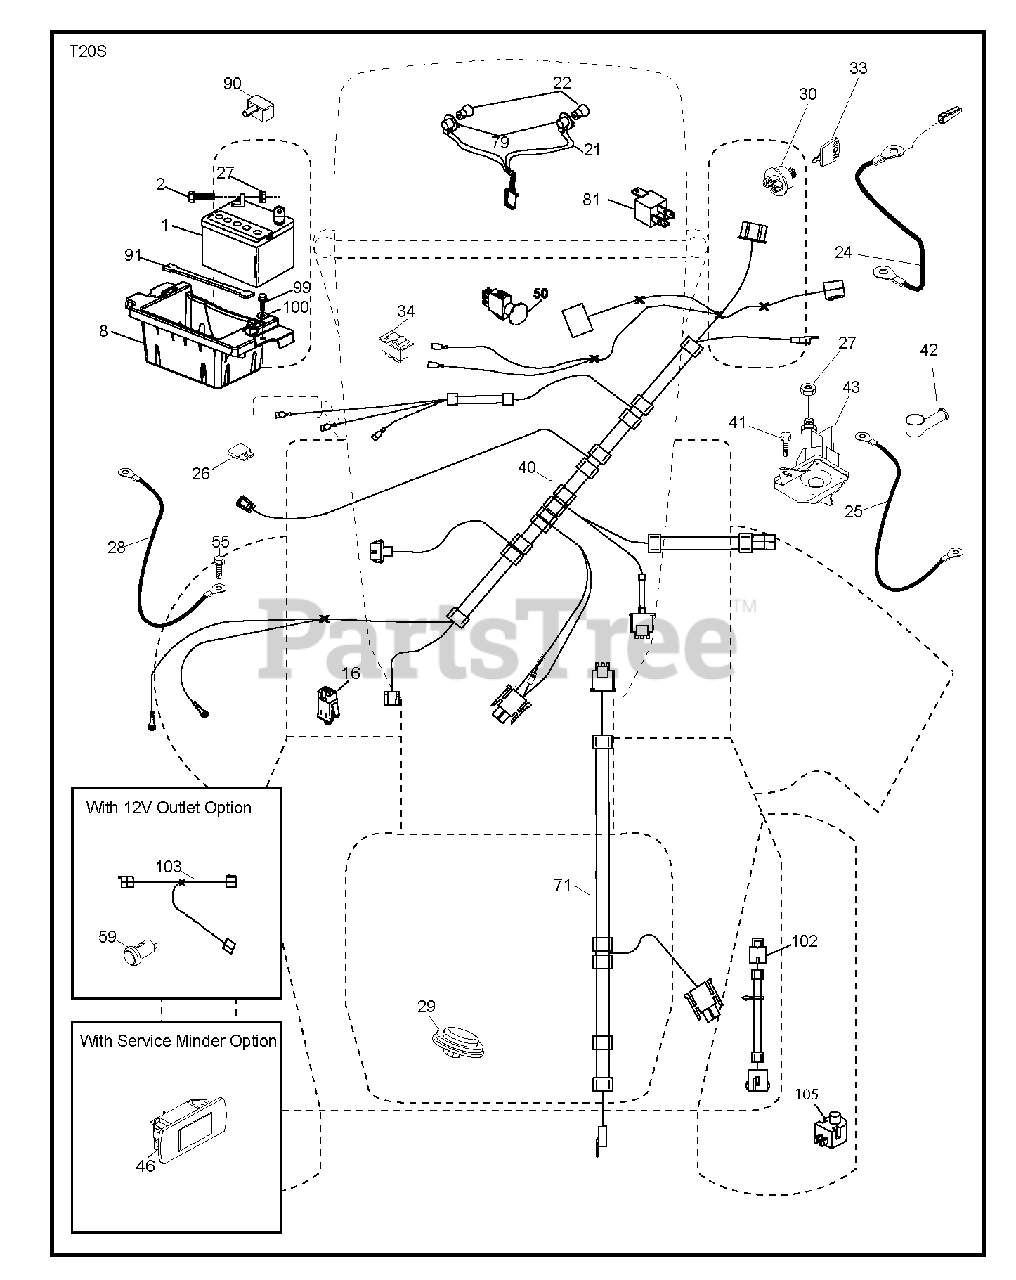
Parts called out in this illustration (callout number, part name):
1	Battery, Dry 30 Amp
2	BOLT.HEX.1/4.X.3/4.DICHROMATE
8	BOX.BATTERY.MOUNT.FRONT.LT
16	SWITCH INTERLOOK PUSH-IN
21	HARNESS.LIGHT W/4152J BULBS
24	CABLE.BATT.POS.WIRE.TG.DA SOL
25	CABLE.STARTER.6G.BL/RED.17.5
26	FUSE 20AMP
27	NUT
28	CABLE GROUND 6 GA 21" 90T BLK
29	SWITCH.SEAT.DELTA.OPC.
30	SWITCH.IGN.DELTA.W.LGH.ROS
33	KEY.CHAIN.BLISTER.PACK.GEN.USA
40	HARNESS.IGN.ELE.RELAY.TEX.46"
41	SCREW
42	TERMINAL COVER
43	SOLENOID.W/BRASS.PLUNGER
46	RP GUAGE.SRVCMNDR.HRMTR.
50	RB PTO.SWITCH.8 TERMINAL.BLACK
55	SCREW 5/16"
71	HARNESS-CHASSIS SUB
79	BULB HOLDER ASM.
81	RELAY HARNESS.SEALED
90	COVER.TERMINAL.BATTERY
91	STRAP.BATTERY.MOUNT.FRONT(2 2)
99	SCREW HEXWSHR 1/4-20X3/4
102	HARNESS PIGTAIL PCH TEX ROS
105	REVERSE SWITCH
